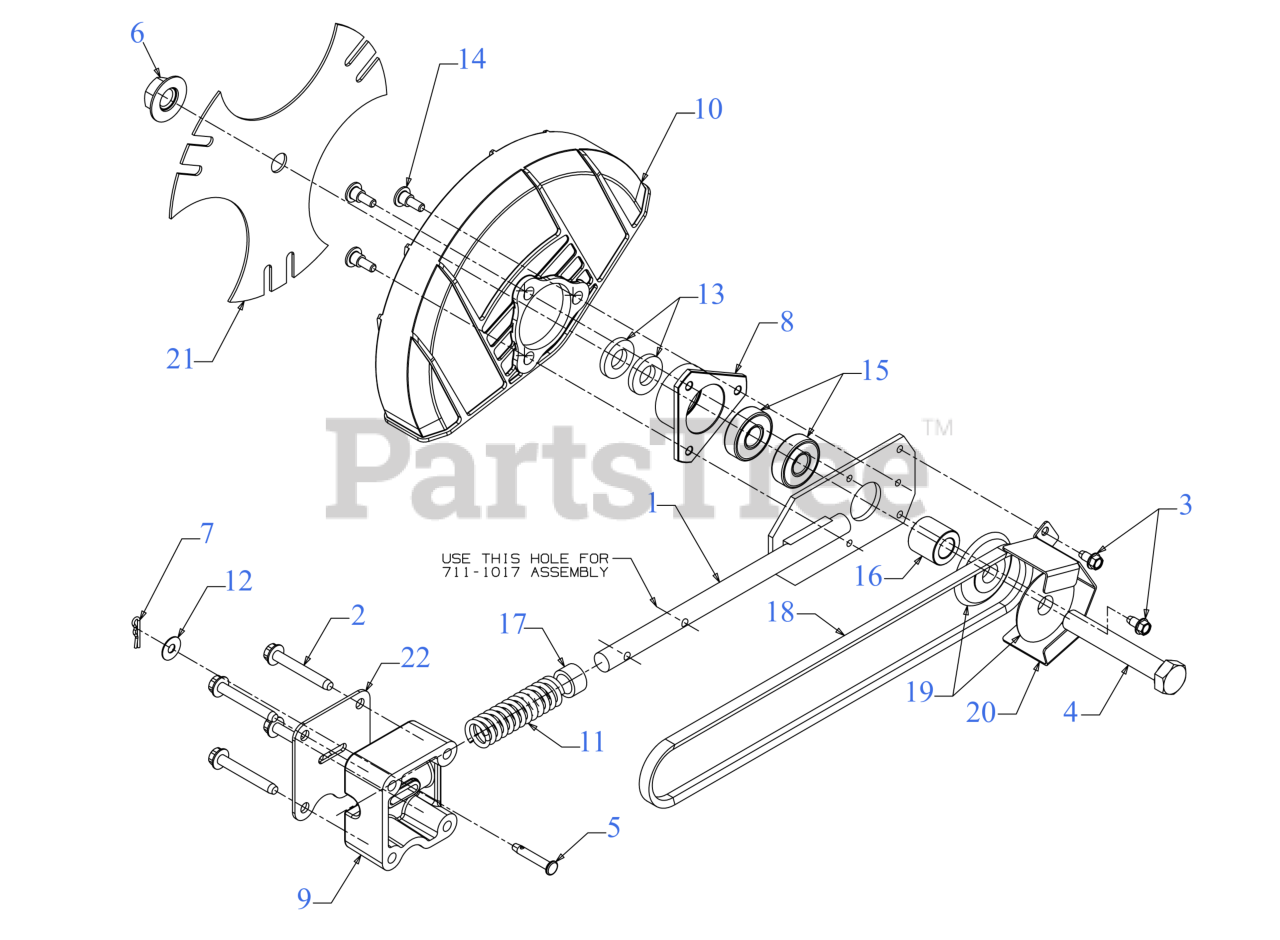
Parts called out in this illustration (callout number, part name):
1	BLADE PLATE ASSEMBLY
3	SCREW 1/4-20 X.500
4	SCREW 5/8-18 x 4 GR5
5	CLEVIS PIN
6	HEX NUT
7	COTTER PIN .072 DIA. 1.13 LG
8	BEARING CUP
9	BEARING BLOCK
10	EDGER BLADE GUARD (W/LABEL)
11	COMPRESSION SPRING
12	FLAT WASHER .283 ID x .749 x .030
13	FLAT WASHER .635X1.24X.181
14	SHOULDER SCREW .375X.280:1/4-14
15	BALL BEARING
16	SPACER
17	SPACER
18	BELT 3L x 35.80
19	SHEAVE
20	BELT GUARD (POWDER BLACK)
